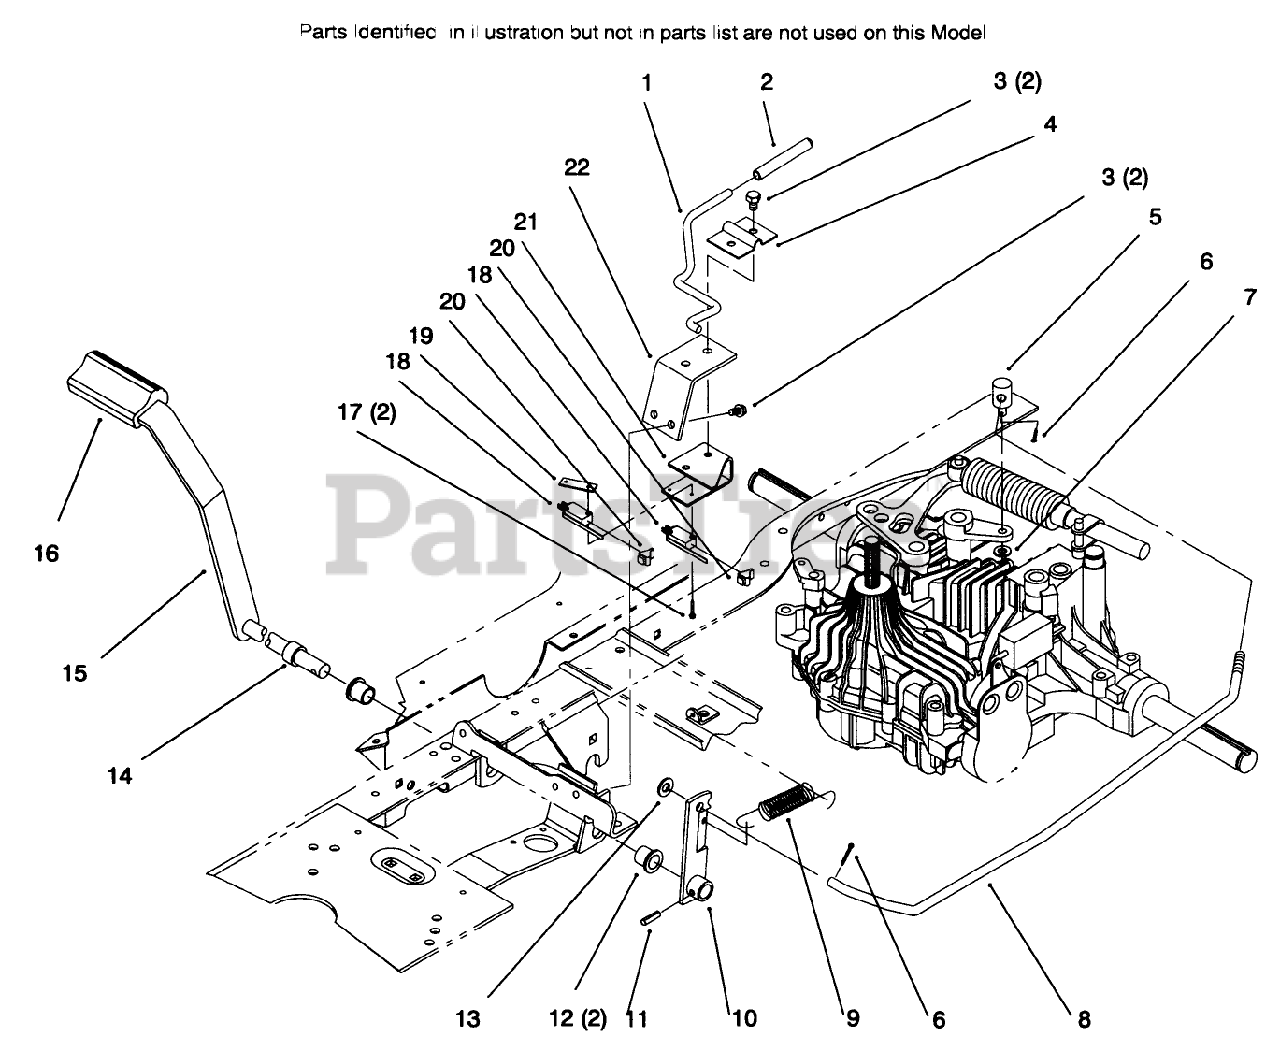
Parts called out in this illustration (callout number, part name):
1	ROD - PARKING BRAKE
2	GRIP - PARKING BRAKE
3	SCREW-HWHTF
4	BRACKET-PARKING BRAKE
5	TRUNNION - BRAKE
6	PIN-COTTER
7	WASHER-PLAIN
10	BRAKE LEVER ASM
11	PIN-SPRING
12	BUSHING-FLANGE
13	WASHER-FLAT
14	SPACER-BRAKE
15	LEVER - BRAKE ASM
16	PAD-PEDAL
17	SCREW-HH
18	SWITCH-MICRO
19	NUT-SPEED
20	PLUNGER-SEAL
21	BRACKET-BRAKE SWITCH
22	SUPPORT-P. BRAKE
